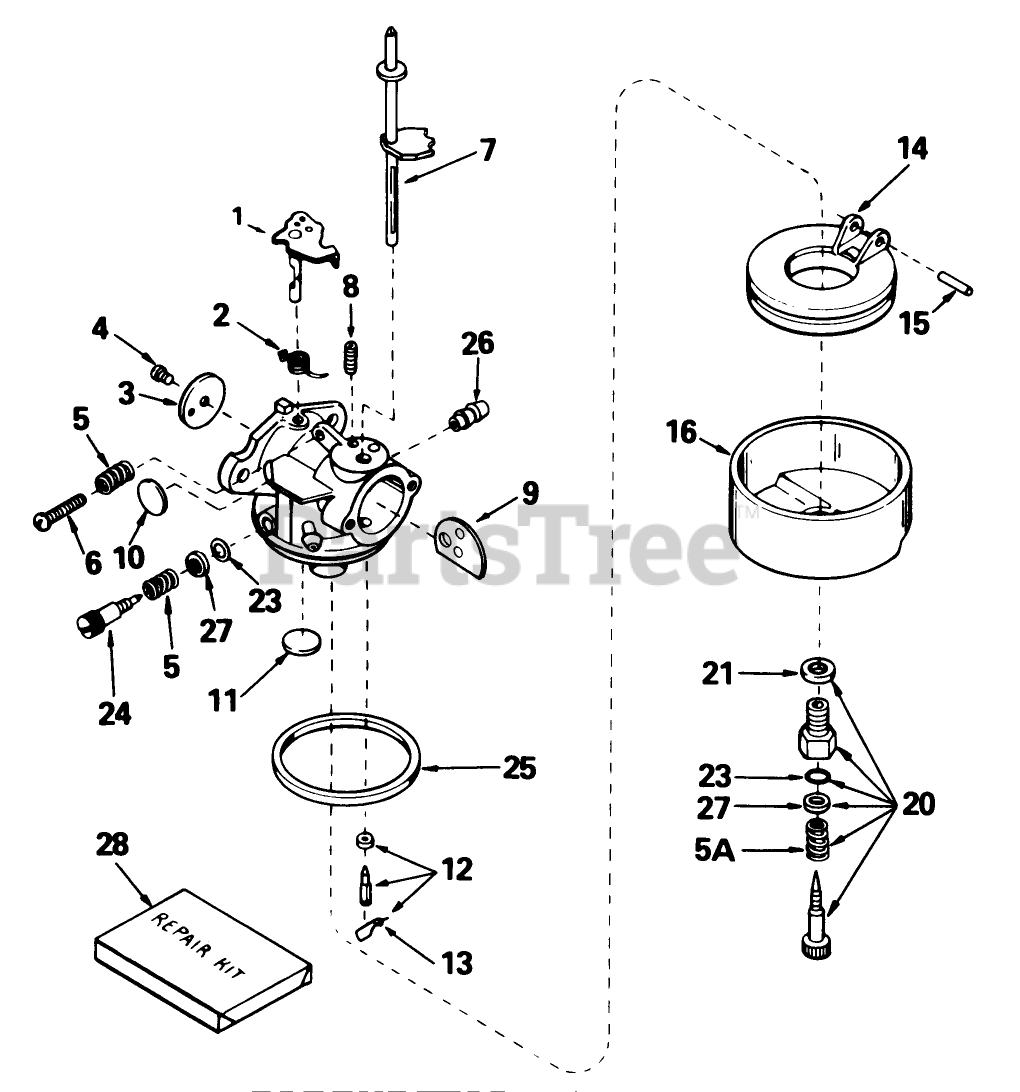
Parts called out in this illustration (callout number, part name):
1	Shaft/Lever-Throttle
2	Spring-Return, Throttle
3	Shutter-Throttle
4	Screw-Shutter
5	Spring-Tension
5A	Spring
6	Screw-Throttle Crack Screw / Idle Speed
7	Shaft-Choke
8	Spring-Positioning, Choke
9	Shutter-Choke
10	Plug-Welch, Idle Mixture Well
11	Plug-Welch, Atmospheric Vent
12	Inlet Needle, Seat Clip Assy. (Incl. No. 13)
13	Clip-Spring
14	Float
15	Shaft-Float
16	Bowl-Float (no drain)
20	Adjustment Screw Assy., Main (Incl. Nos. 5A, 21 23)
21	Washer-Bowl Nut
23	ORing
24	Screw, Idle Adj.
25	O Ring-Bowl, Float
26	Fitting-Fuel
27	Washer
28	Repair Kit (Incl. items marked *)
